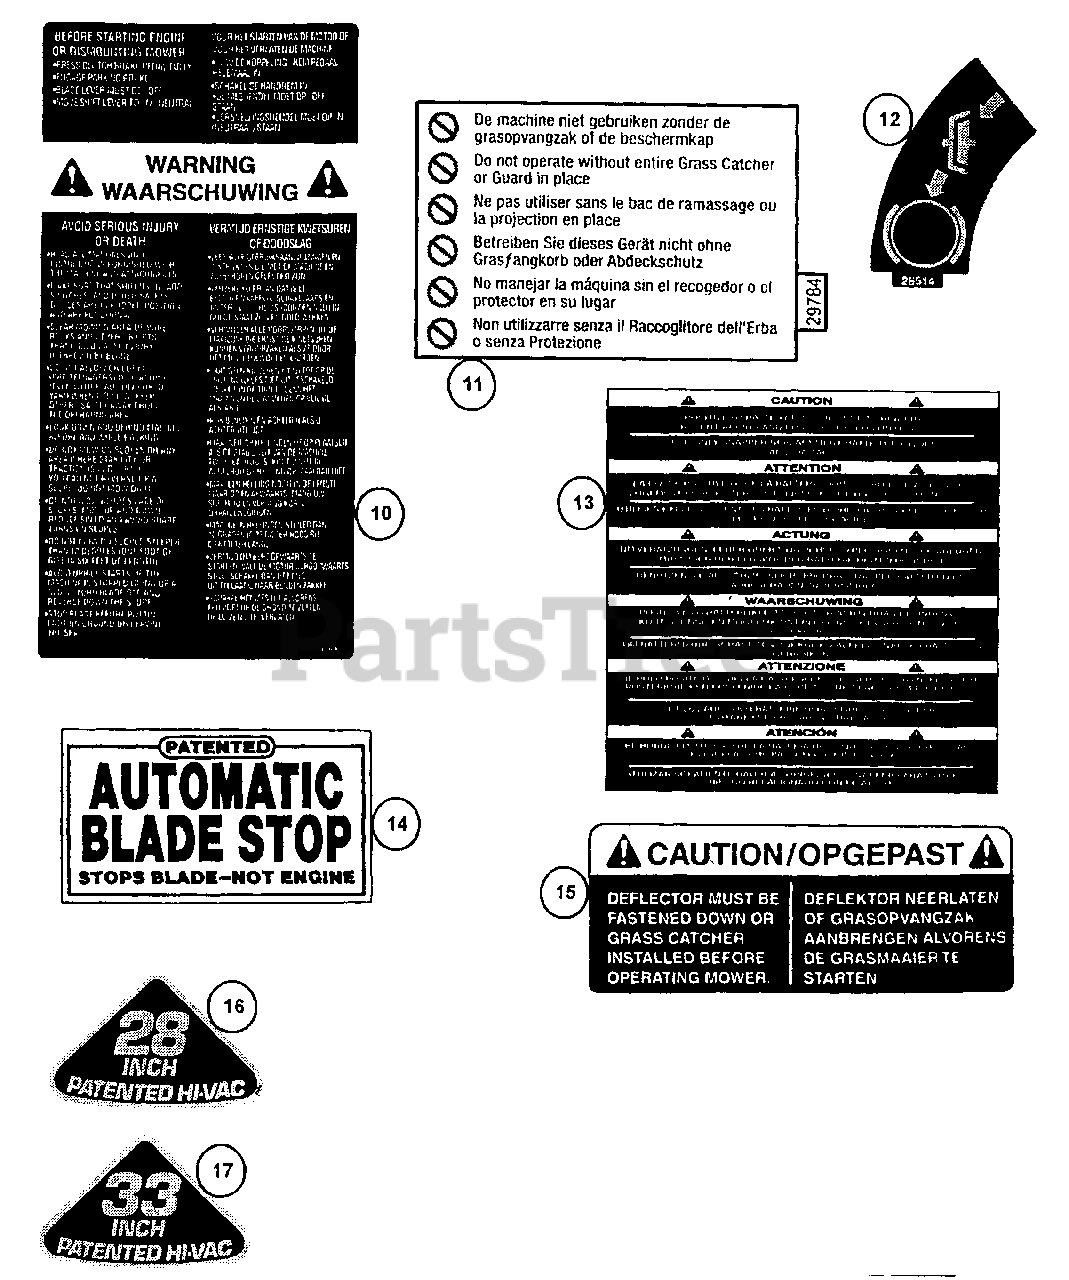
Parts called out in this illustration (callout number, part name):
10	DECAL, SAFETY Instruction (English & Dutch)
11	DECAL, DO NOT OPERATE!
12	DECAL, Clutch/Brake
13	DECAL, Battery CAUTION
14	DECAL, Automatic Blade Stop
15	DECAL, Deflector CAUTION (English & Dutch)
16	DECAL, 28 Inch (Hi-Vac)
17	DECAL, 33 Inch (Hi-Vac)
